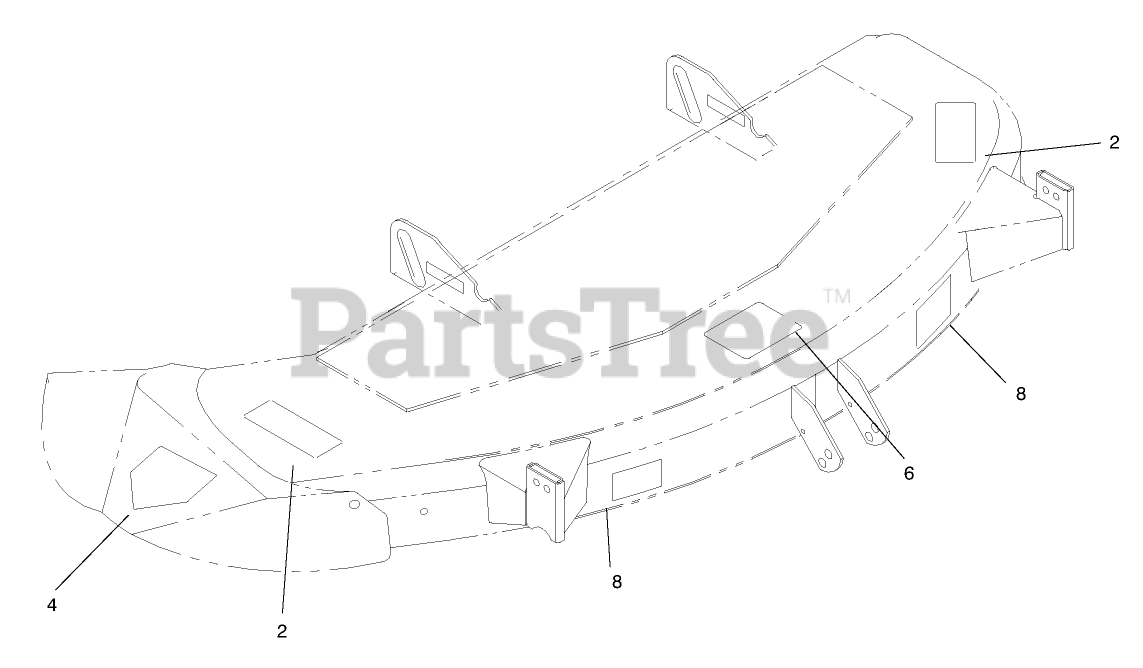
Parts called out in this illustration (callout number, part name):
2	DECAL-DANGER
4	DECAL-DANGER
6	DECAL-BELT INSTALL
8	DECAL - WHEEL ADJUSTMENT
